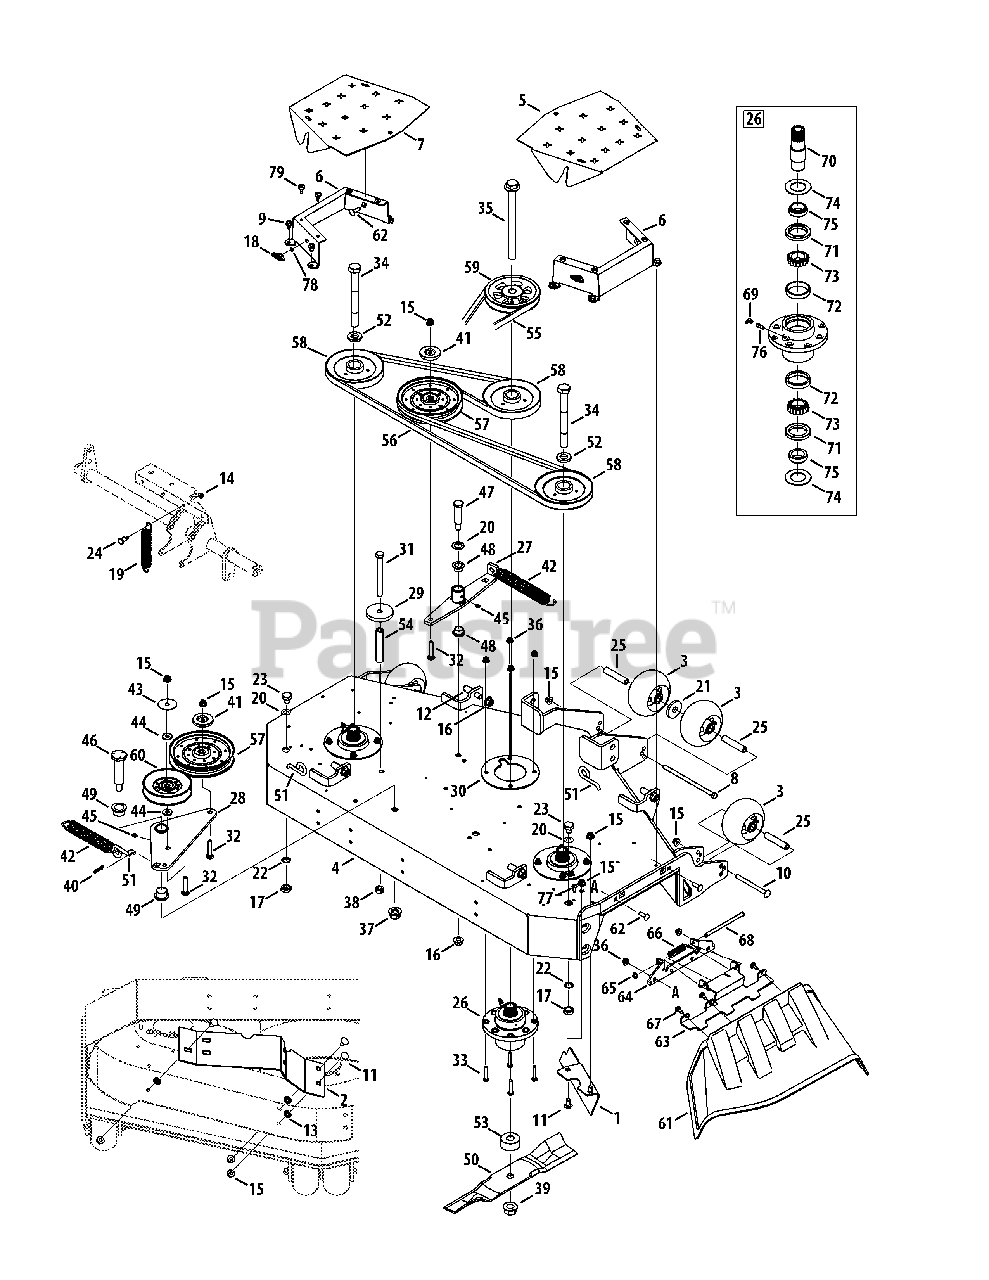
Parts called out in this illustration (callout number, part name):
2	Baffle, 60" Adjustment
3	Complete Wheel, 5.00 Dia.
5	Deck Belt Cover, RH
6	Deck Belt Cover Bracket
7	Deck Belt Cover, LH
8	Hex Cap Screw, 3/8-16 x 7.25
9	Screw, 5/16-18 x .500
10	Carriage Screw, 3/8-16 x 4.50
11	Carriage Bolt, 3/8-16 x .750
12	Pin, 1/2-13 x .625 x 1.2
13	Push Nut, 3/8
14	Nut, 1/4-20, Flangelock
15	Nut, 3/8-16, Flangelock
16	Nut, 1/2-13, Flangelock
17	Hex Nut, M16-1.5
19	Extension Spring, .969 x 6.180
20	Washer, .793 x 1.24 x .06
21	Flat Washer, .632 x 1.00 x .160
22	Lock Washer, 17 x 23.8 x 1.95
23	Plug, Screw, M16-1.5
24	Shoulder Bolt, .437 x .50, 1/4-20
25	Wheel Spacer
26	Spindle Assembly
27	Deck Idler Arm
28	Idler Assembly
29	Spacer, .5375 x 2.75 x .375
30	Spindle Support Plate
31	Hex Cap Screw, 1/2-13 x 5.00
32	Screw, 3/8-16 x 2.00
33	Bolt, 5/16-18 x 1.25
34	Hex Cap Screw, 3/4-16 x 7.00
35	Hex Cap Screw, 3/4-16 x 9.00
36	Nut, 5/16-18, Flangelock
37	Nut, 5/8-18, Flangelock
38	Nut, 1/2-13, Hexlock
39	Nut, 3/4-16, Flangelock
40	Bow Tie Cotter Pin
41	Pulley Cap
42	Extension Spring, 1.248 x 8.5
43	Washer, .406 x 1.92 x .060
44	Washer, .406 x 1.00 x .105
45	Grease Fitting
46	Shoulder Bolt, 1.0 x 3.15, 5/8-18
47	Shoulder Bolt, .750 x 2.23, 1/2-13
48	Flange Bearing, .75 x .52
49	Flange Bearing, 1.00 x .75
50	Hi-Lift Blade, 21.0
51	Spring Rod Hook
52	Spacer, .812 x .218
53	Spacer, .760 x 2.00 x .925
54	Spacer, .405 x .75 x 3.875
57	Idler Pulley
58	Spindle Pulley
59	Drive Pulley
60	Idler Pulley
61	Discharge Chute Assembly
62	Carriage Bolt, 5/16-18 x 1.00
65	Push Cap
66	Torsion Spring
67	Shoulder Screw, 1/4-20
68	Chute Rod
69	Grease Fitting, 45 degree, 1/4-28
70	Spindle Shaft
71	Seal, Oil
72	Cup Bearing
73	Cone Bearing
74	Washer, 1.50 x 2.52 x .075
75	Ring, Seal
76	Straight Adapter Fitting
77	Hex Flange Screw, 1/4-20 x .500
78	Speed Nut, .3125
79	Bumper, .62 Dia. x .3
